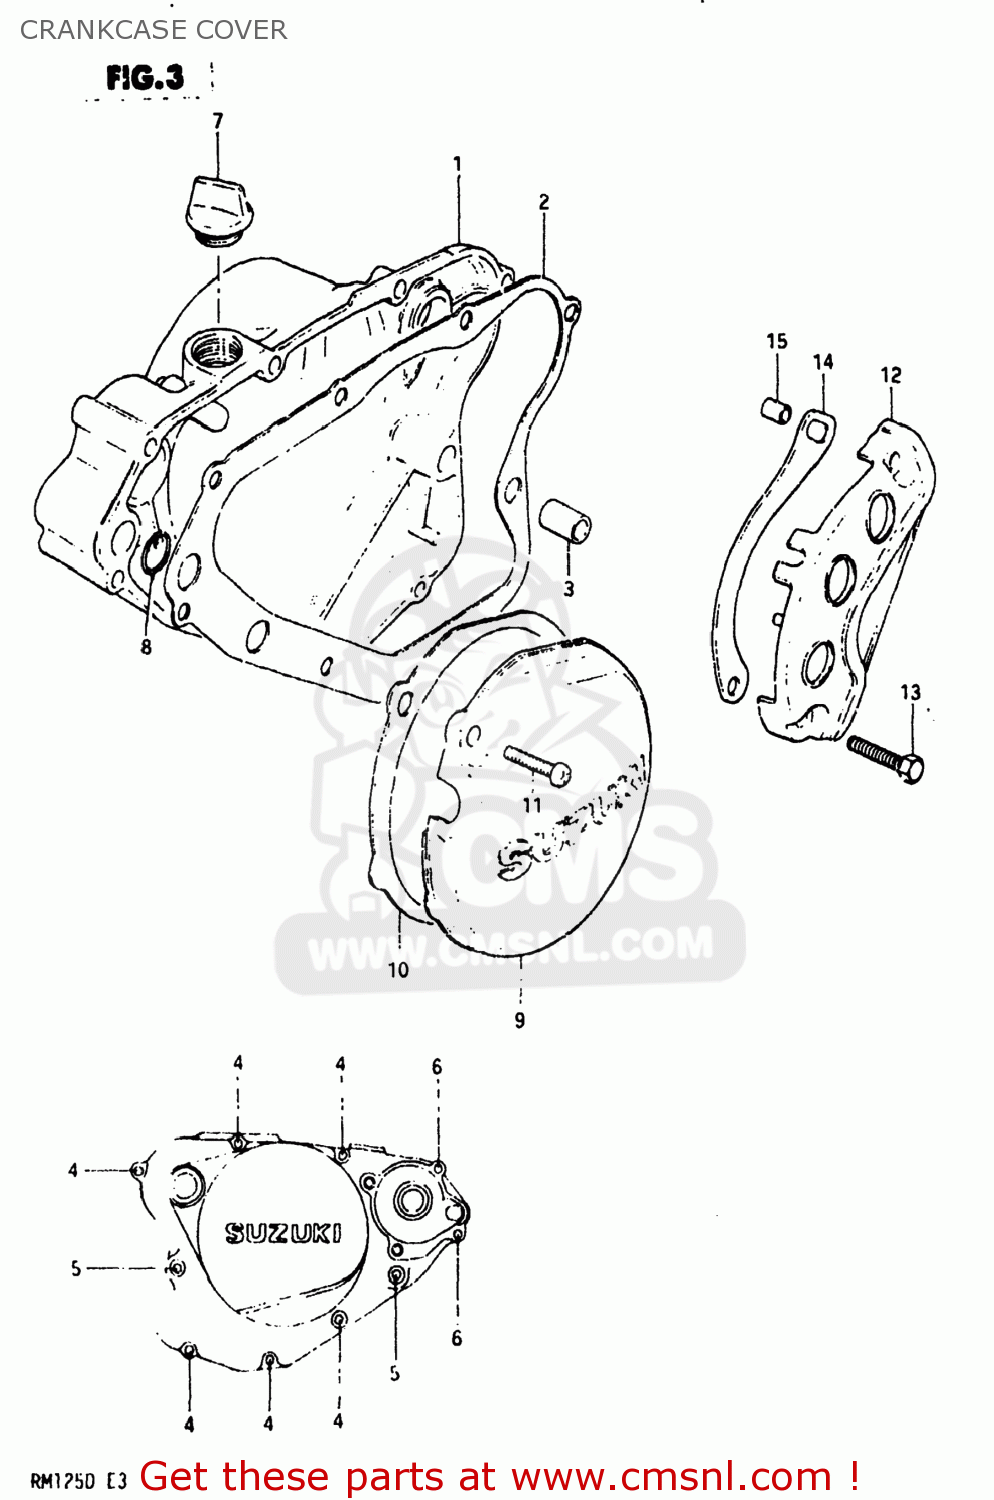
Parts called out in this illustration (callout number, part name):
1	COVER,CLUTCH
2	GASKET,CLUTCH COVER (MCA)
3	PIN
4	SCREW
5	SCREW (6X45)
6	SCREW 6X70
7	PLUG,OIL FILTER
8	O RING(D:1.9,ID:14.5)
9	COVER,MAGNETO
10	GASKET,MAGNETO COVER (NAS)
11	SCREW
12	COVER,ENGINE SPROCKET
13	BOLT
14	PLATE,CHAIN FRONT GUIDE
15	SPACER(6.5X10.5X12)
